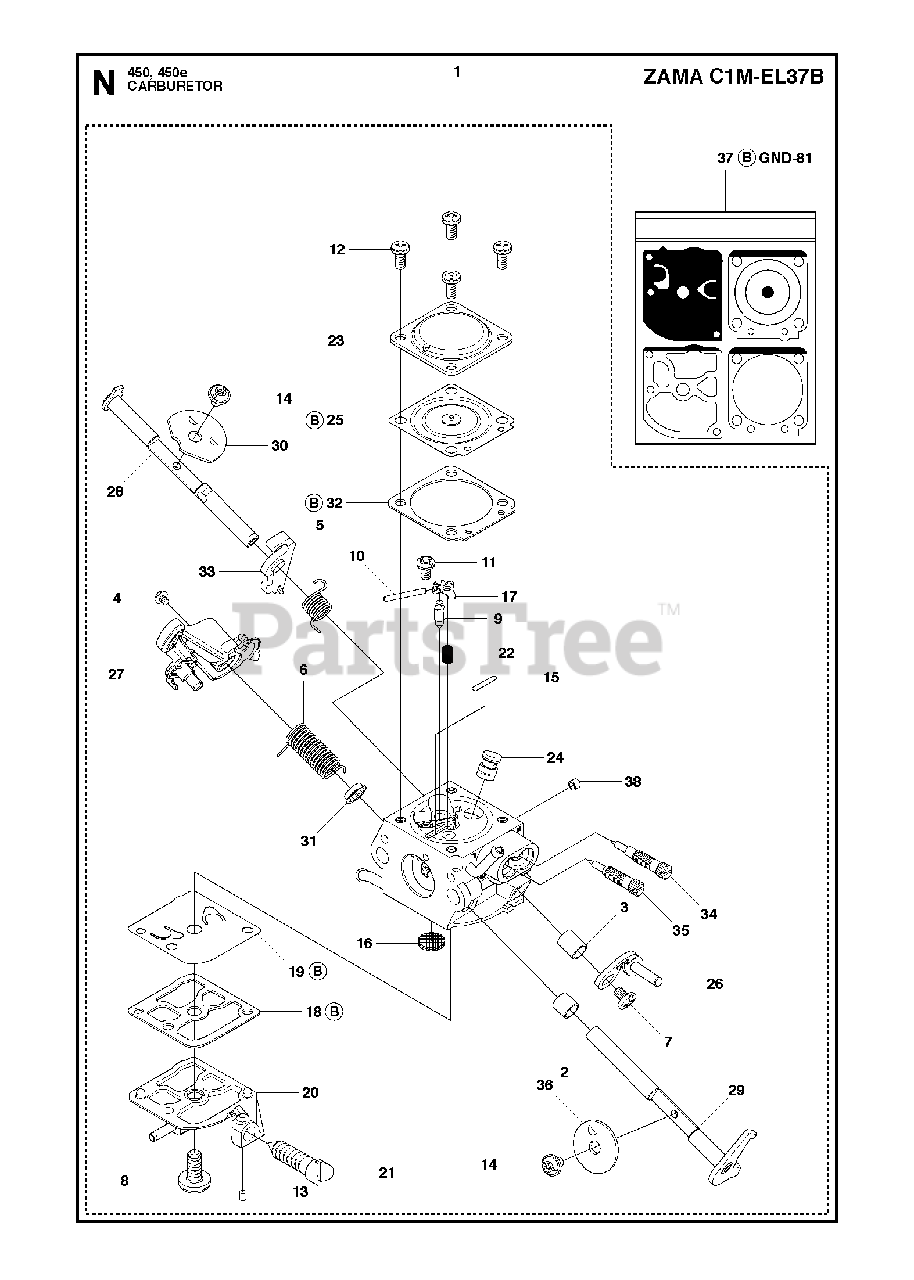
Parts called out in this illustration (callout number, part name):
1	CARBURETOR
2	COLLAR
3	COLLAR
4	SCREW
5	SPRING
6	SPRING
7	SCREW
8	SCREW
9	INLET NEEDLE
10	PIN FULCRUM
11	SCREW
12	SCREW
13	PLUG
14	SCREW
15	PLUG
16	STRAINER
17	LEVER
18	GASKET
19	PUMP DIAPHRAGM
20	COVER
21	SCREW
22	SPRING
23	COVER
24	JET
25	DIAPHRAGM
26	LEVER
27	THROTTLE LEVER
28	Shaft Assembly
29	Shaft Assembly
30	VALVE
31	COLLAR
32	GASKET
33	LEVER
34	SCREW
35	SCREW
36	VALVE
37	GASKET KIT
38	PLUG
